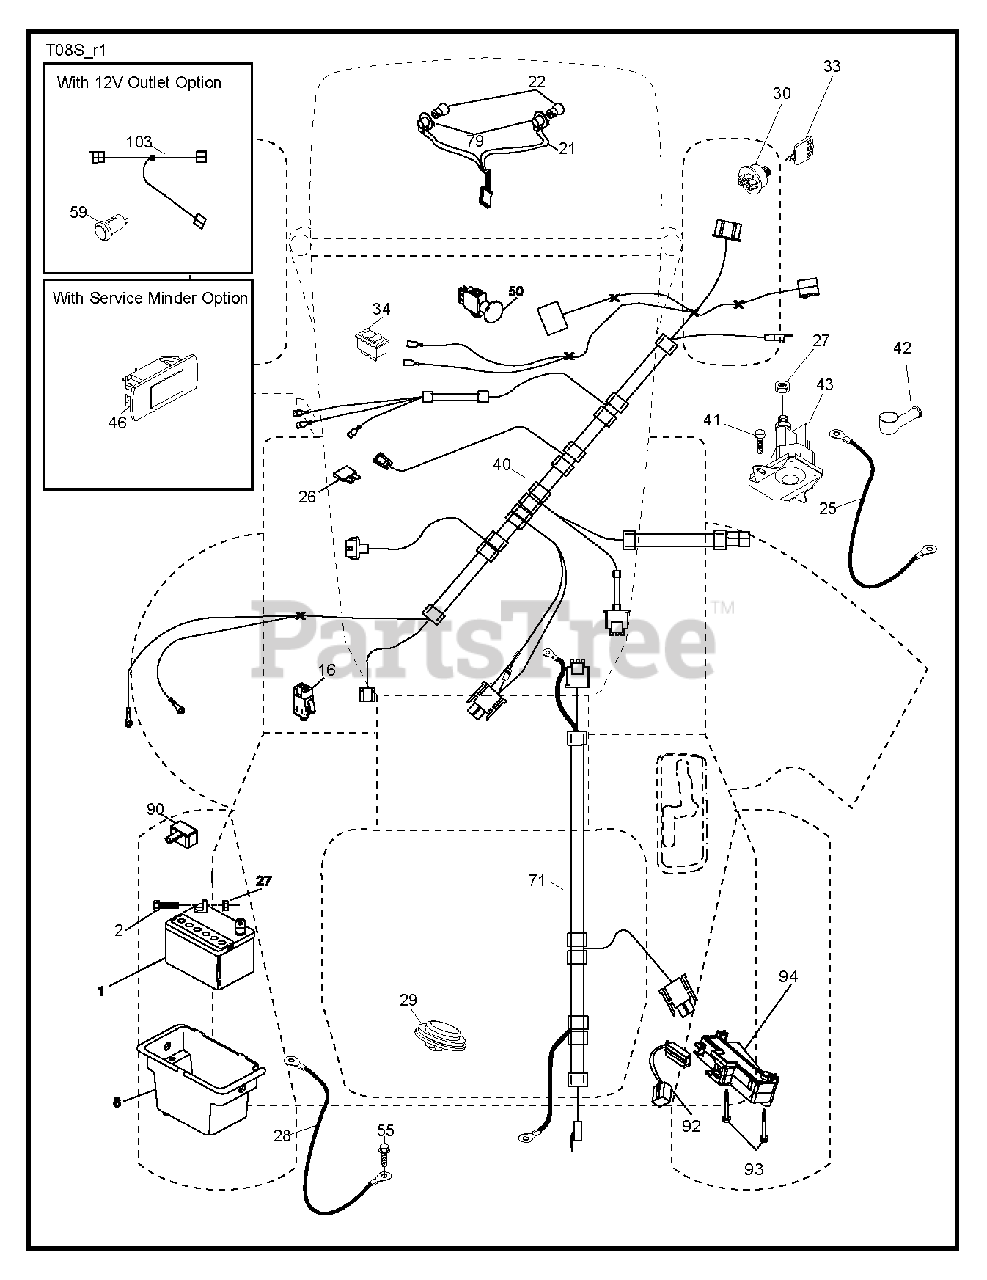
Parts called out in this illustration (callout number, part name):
1	REPL BY 532 12 38-99
8	BOX.BATTERY.MNT.REAR.L
16	SWITCH INTERLOOK PUSH-IN
21	HARNESS.LIGHT W/4152J BULBS
22	LIGHTBULB
25	CABLE.STARTER.6G.BL/RED.17.5
26	FUSE 20AMP
27	NUT
28	CABLE.BLACK.18"REAR.BA
29	SWITCH.SEAT.DELTA.OPC.
30	SWITCH.IGN.DELTA.W.LGH.ROS
33	KEY.CHAIN.BLISTER.PACK.GEN.INT
34	SWITCH LT
40	HARNESS.IGN.DASH.HUQ/P
41	SCREW
42	TERMINAL COVER
43	SOLENOID.W/BRASS.PLUNG
46	GUAGE.SRVCMNDR.HRMTR.
50	PTO SWITCH
55	SCREW 5/16"
71	HARNESS.IGN.CHASS.TEX.REAR.BAT
79	BULB HOLDER ASM.
90	COVER, TERMINAL BATTERY
92	HARNESS.PIGTAIL.CONSLE
93	SCREW.PLASTITE
94	MODULE.REVERSE.ROS
